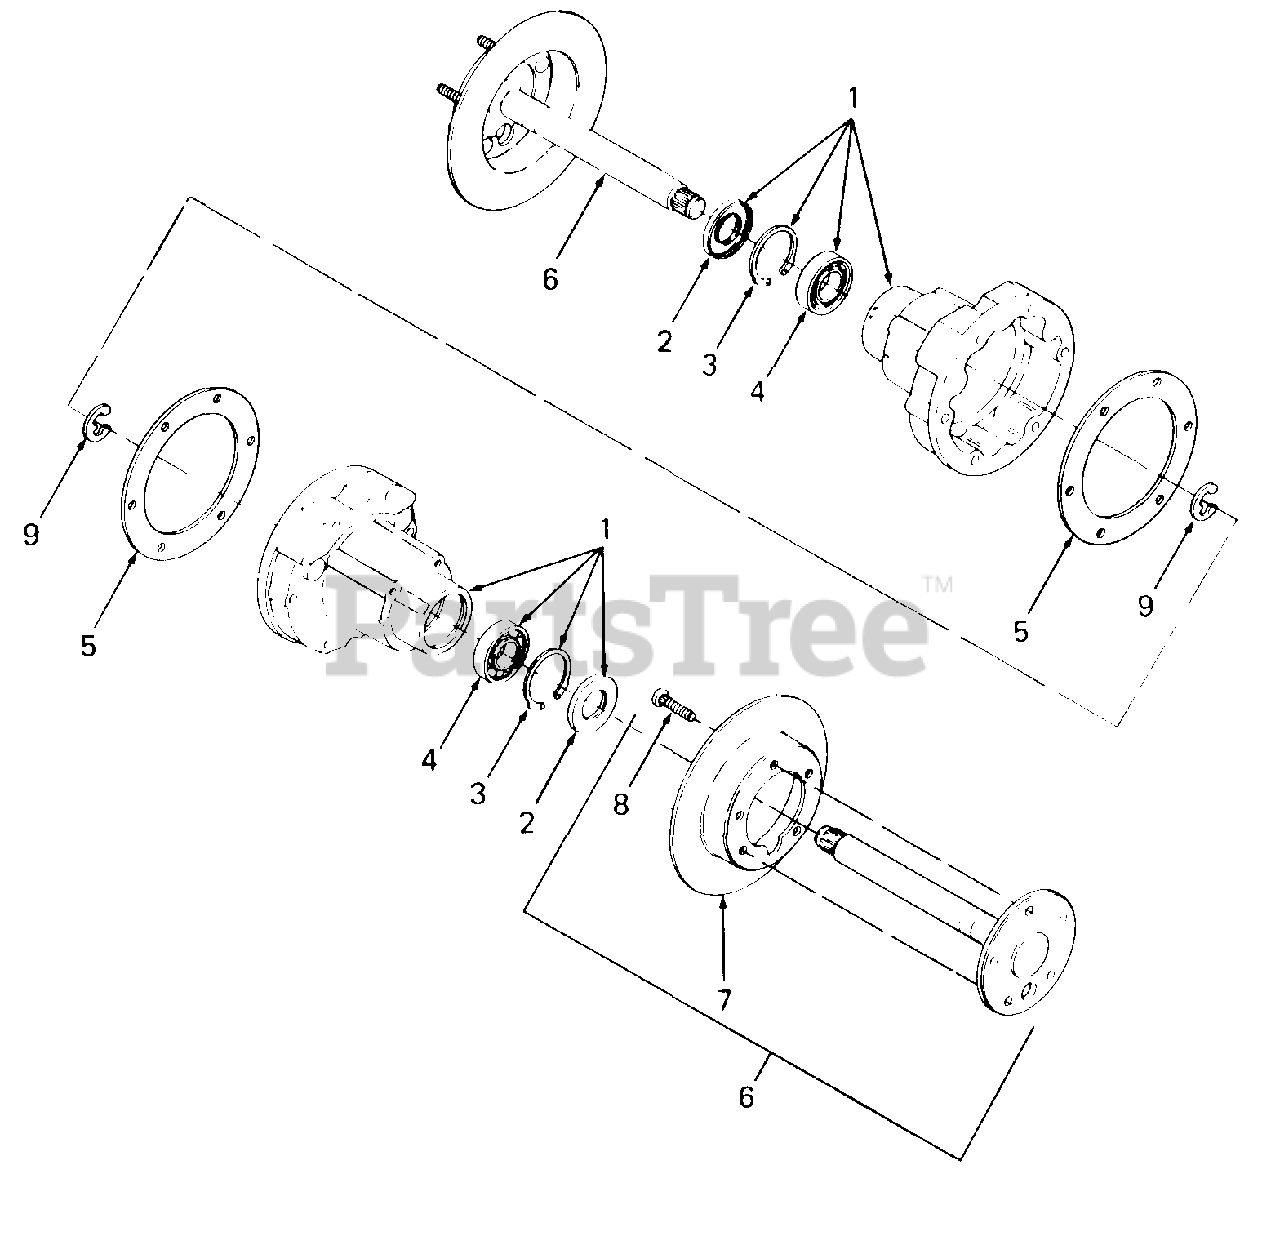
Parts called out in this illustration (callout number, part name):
1	Carrier Assy, Rear Axle
2	Seal, Oil
3	Ring, Retaining
4	Bearing, Ball
5	Gasket, Carrier
6	Axle Assy, Rear
7	Disc, Brake
8	Bolt, Lug
9	Retainer, E-Ring
